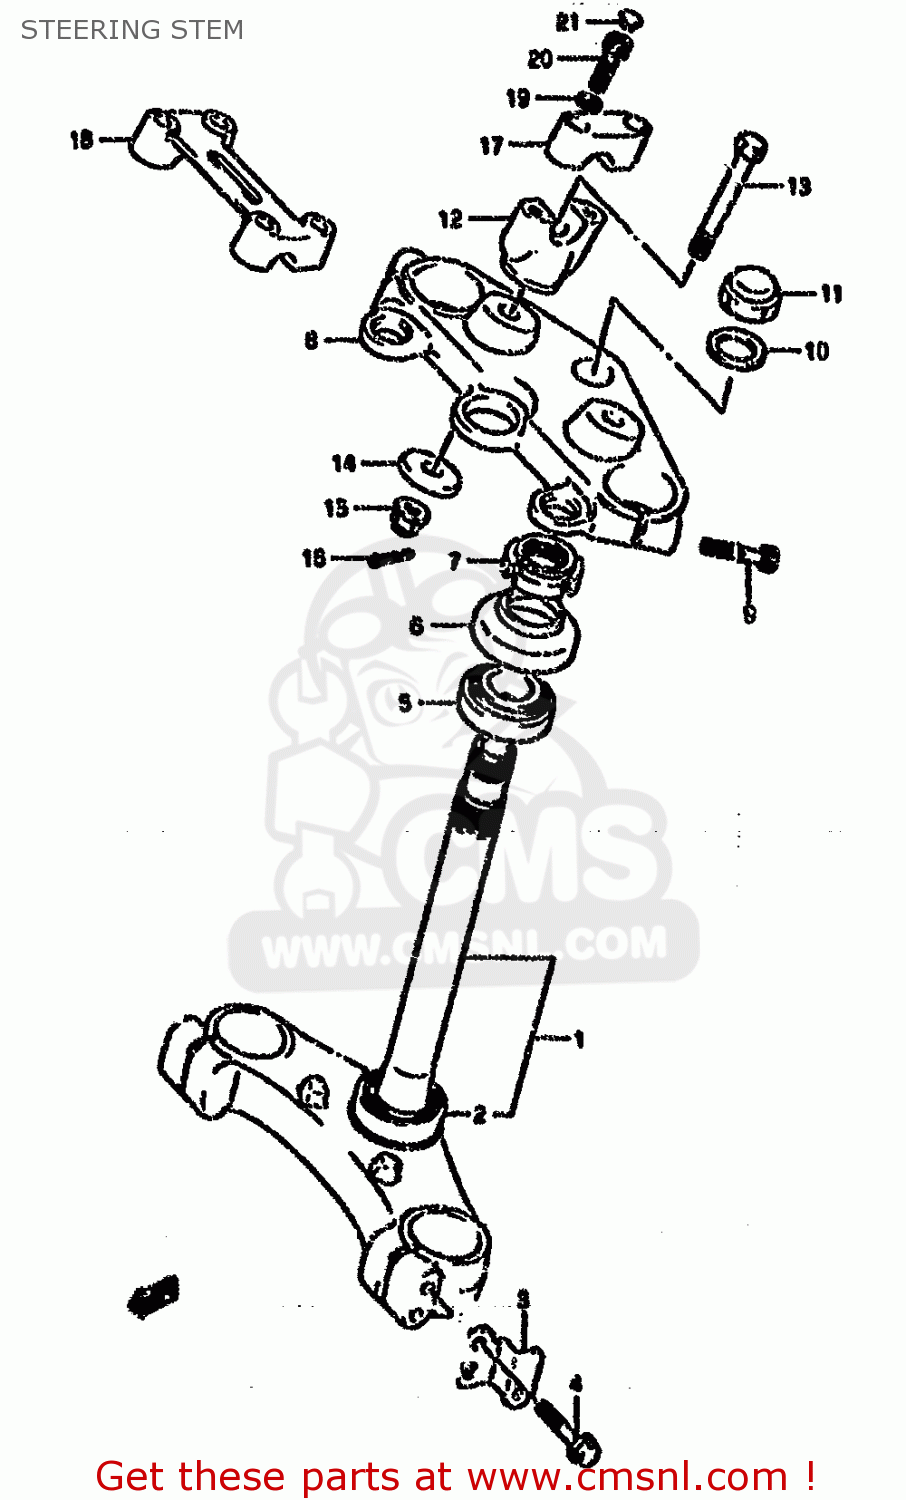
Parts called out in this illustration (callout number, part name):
1	STEM,STEERING
2	BEARING(30X55X17)
3	BRACKET,SIDE REFLECTOR
4	BOLT,STEM HEAD(8X40)
5	TAPER,ROLLER BEARING
6	SEAL,STEERING UPR DUST
7	NUT,STEERING STEM(25X44X10)
8	HEAD,STEERING STEM
9	BOLT
10	WASHER(22.5X32X1.6)
11	NUT,CAP
12	HOLDER,HANDLE LWR
13	BOLT
14	WASHER,FRONT FORK
15	NUT
16	PIN 20X20
17	HOLDER,HANDLEBAR
18	HOLDER,HANDLE UPR
19	WASHER
20	BOLT
21	CAP(OD:14.5)
